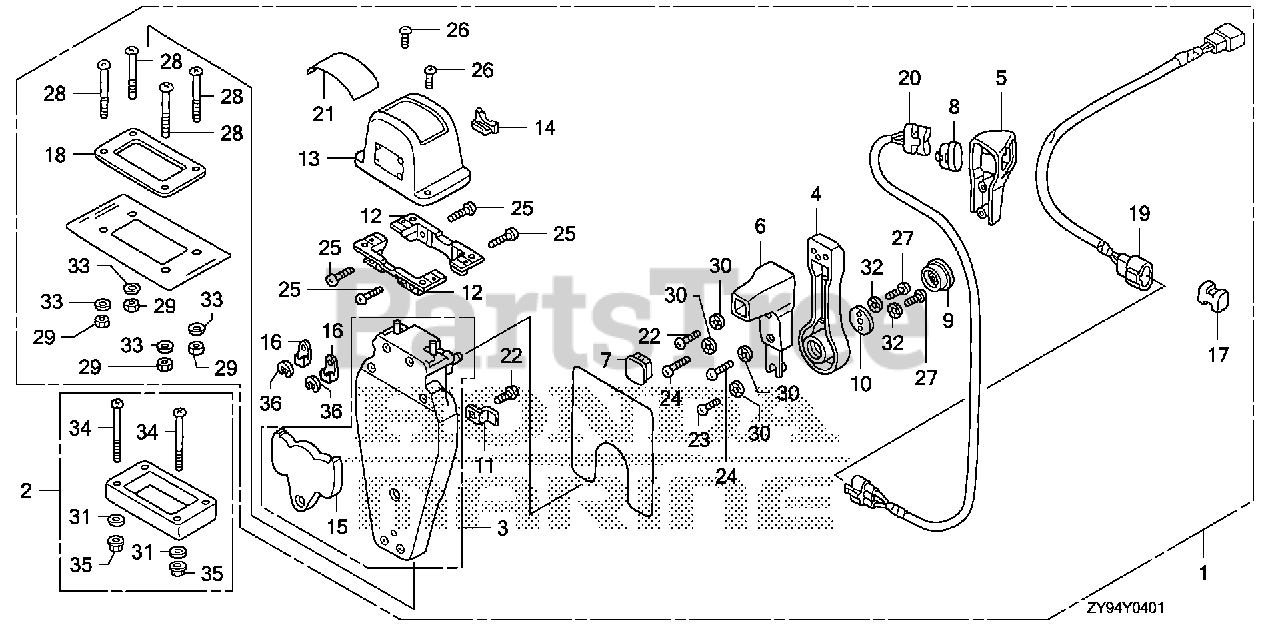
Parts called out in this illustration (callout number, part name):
1	BOX KIT, L. REMOTE CONTROL (TOP MOUNT SINGLE)
2	SPACER KIT, REMOTE CONTROL BOX (TOP MOUNT SINGLE)
3	HOUSING ASSY., R. (INNER) (TOP MOUNT)
4	HANDLE, REMOTE CONTROL
5	COVER, R. GRIP
6	GRIP, REMOTE CONTROL HANDLE
7	CAP, GRIP
8	CAP, SWITCH
9	BUTTON, THROTTLE
10	PLATE, HANDLE
11	PLATE, CABLE CLAMP
12	BRACKET, REMOTE CONTROL HOUSING
13	HOUSING, REMOTE CONTROL BOX
14	HOUSING, LEAD
15	PLATE, DWELL
16	TERMINAL, CABLE
17	SPACER, CABLE CLAMP
18	GASKET, SINGLE
19	SUB-HARNESS ASSY., POWER TRIM-TILT (B)
20	SWITCH ASSY., POWER TRIM-TILT
21	MARK, REMOTE CONTROL (SINGLE)
22	SCREW, PAN (5X16)
23	SCREW, PAN (5X10)
24	SCREW, PAN (5X20)
25	SCREW, PAN (5X18)
26	SCREW, PAN (4X10)
27	SCREW, PAN (6X18)
28	SCREW, PAN (5X40)
29	NUT, HEX. (5MM)
30	WASHER, LOCK (5MM)
31	WASHER, PLAIN (5MM)
32	WASHER, LOCK (6MM)
33	WASHER, PLAIN (5MM)
34	SCREW, PAN (5X65)
35	NUT, HEX. (5MM)
36	E-RING (6MM)
